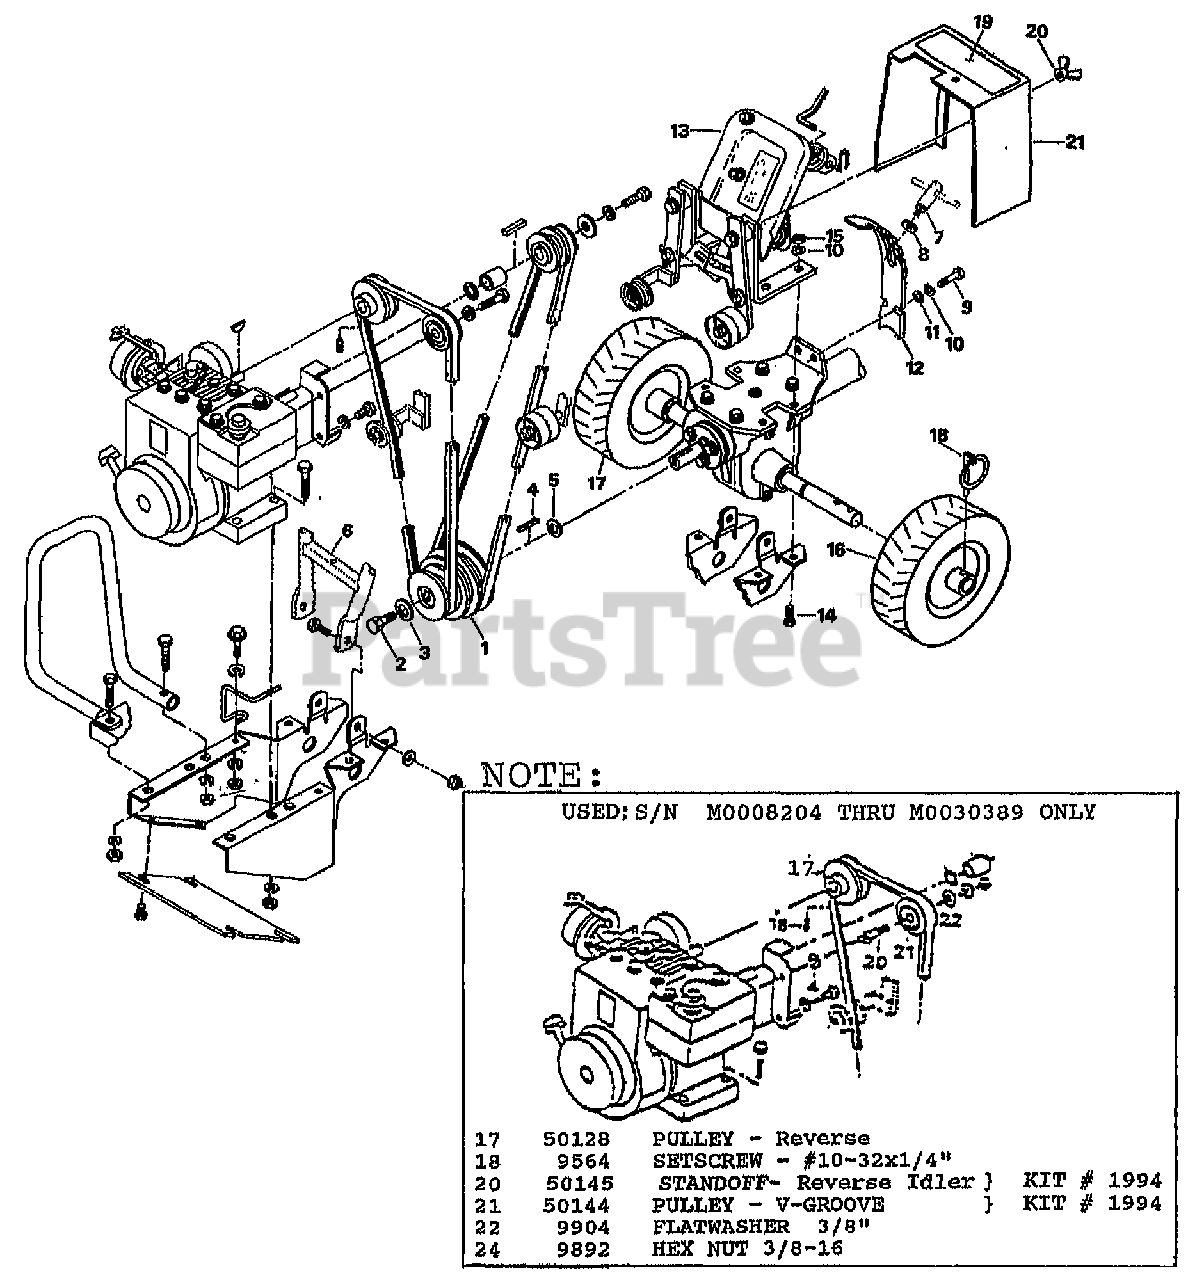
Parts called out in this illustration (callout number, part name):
1	PULLEY-TRANS MACH
2	SCR-HH 5/16-24X.75 G5 ZP
3	WASHER-.827X.331X.098
4	KEY-.188 SQX1.0
5	WASHER-SHLDR HARDENED
6	ASSM-HANDLEBAR
7	ASSM-CLAMP
8	WASHER-FLAT 3/8 SAE
9	SCR-HHC 5/16-18X.75 GR 5 ZP
10	WASHER-LK .312 ZP
11	WASHER-FLAT 5/16 SAE
12	PLATE-HANDLEBAR ADJUST (Handlebar)
13	ASSM-SHIFT MECHANISM
14	SCR-HH 5/16-18X1.25 G5ZP
15	NUT-HEX 5/16-18 ZP
16	ASSM-TIRE&WHL LH GRAY
17	ASSM-TIRE&WHL RH GRAY
17	PULLEY-REVERSE MACH
18	PIN-QUICK RELEASE ZP
18	SCR M10-32X.25
19	DECAL-BELT POSITION
20	NUT-WING/LK 5/16-18 ZP
20	STANDOFF 3/8-16 X 1.88 (Kit #1994)
21	BELT SHROUD W/DECAL-JR.2
21	KIT-REVERSE IDLER-JR2 (Kit #1994)
22	WASHER-FLAT 3/8 SAE
